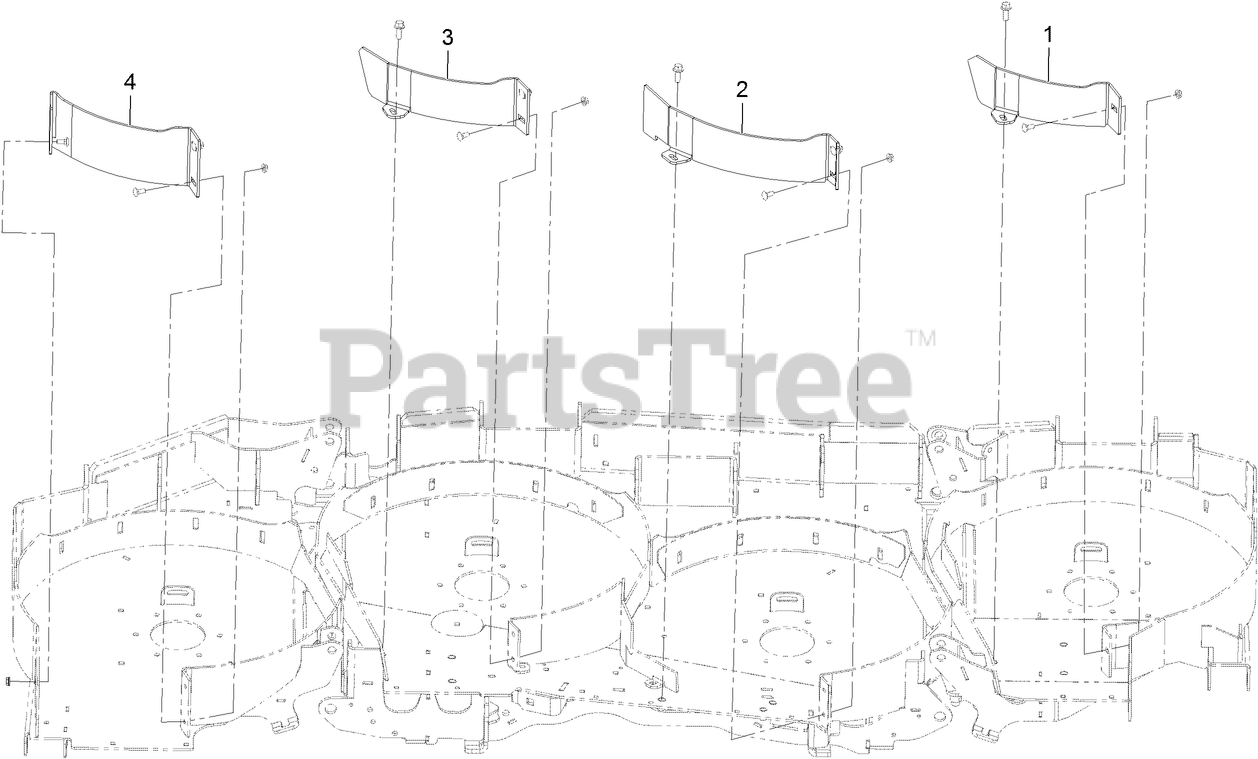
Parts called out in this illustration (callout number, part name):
1	BAFFLE-BLOCK
2	BAFFLE-BLOCK, LH CTR
3	BAFFLE-BLOCK, RH CTR
4	BAFFLE-BLOCK, RH WING
